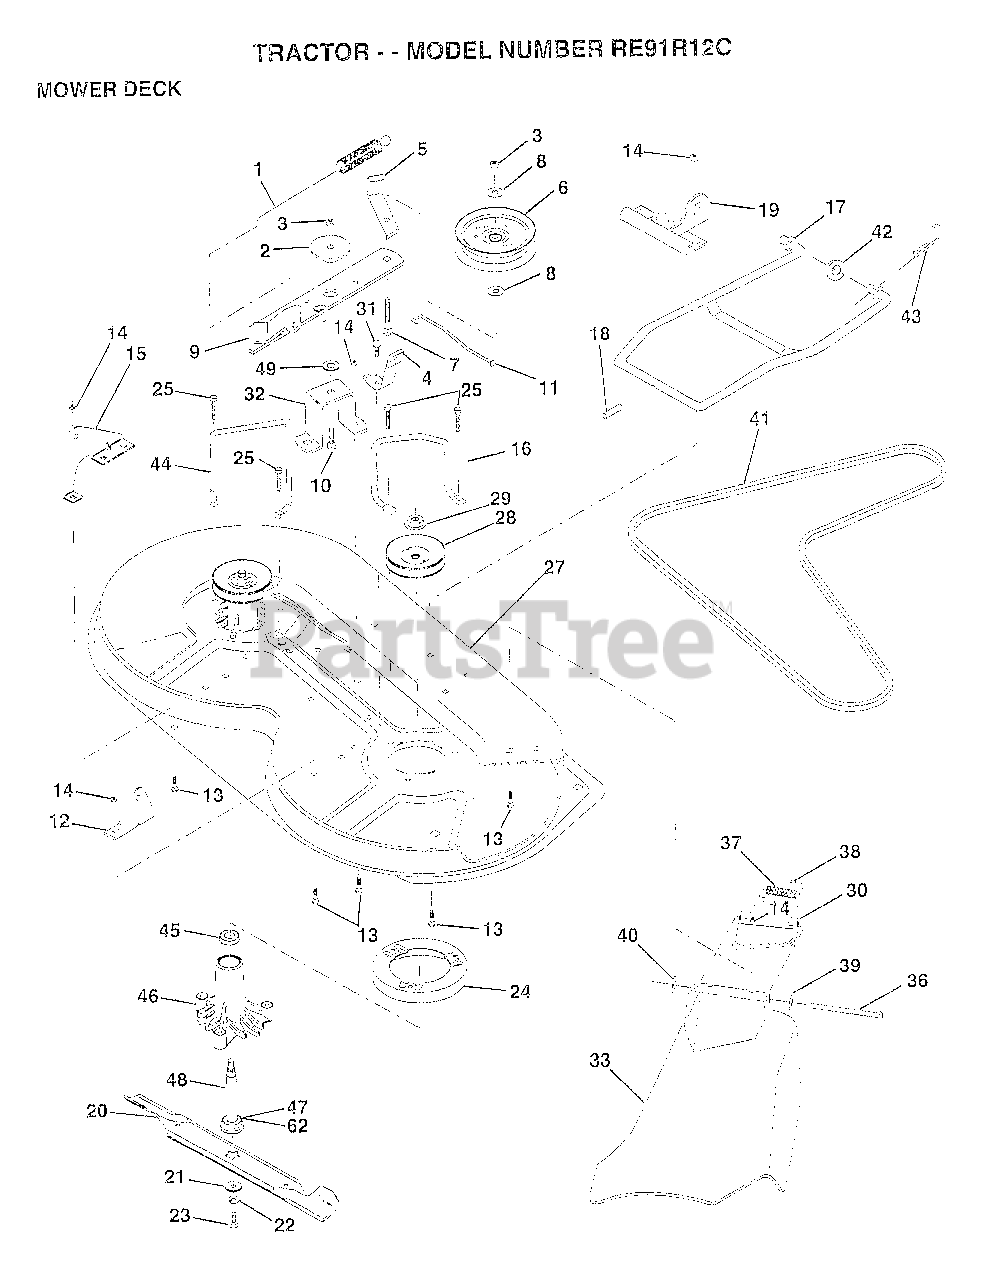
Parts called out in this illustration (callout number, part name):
1	SPRING CLUTCH MWR
2	SPACER RETAINER
4	BRAKE ASM
5	IDLER BELT GUIDE
6	PULLEY IDLER
7	BOLT
8	WASHER
10	BOLT.3/8-14X1.25
11	BRAKE ROD
12	"BRKT,LIFT REAR"
13	BOLT
15	"BRKT,LIFT REAR LH"
16	"KEEPER-BELT,RH"
17	MOWER LINK STAB
18	"PIN,GROOVE"
19	"BRKT,LINK STABILI"
20	"BLADE.36"" HIPERF"
21	WASHER.HARD.BLADE
23	BLADE BOLT
24	STRIPPER RND MWR
25	"SCREW-THD ROLL,WA"
27	"HOUSING-MOWER,36"""
28	PULLEY.MAND.36/46
31	SCREW LT
32	"SUPT,IDLER ARM"
36	HINGE ROD
37	SPRING TORSION
38	CAP-SLEEVE LT
39	WASHER
40	NUT PUSH M
41	V-BELT.PRIM.78.5.
43	RETAINER.SPRING
44	KEEPER BELT LH
45	BEARING
46	HSG ASM MANDREL
47	BEARING.BALL
49	HARDENED WASHER
62	WASHER.FELT.
